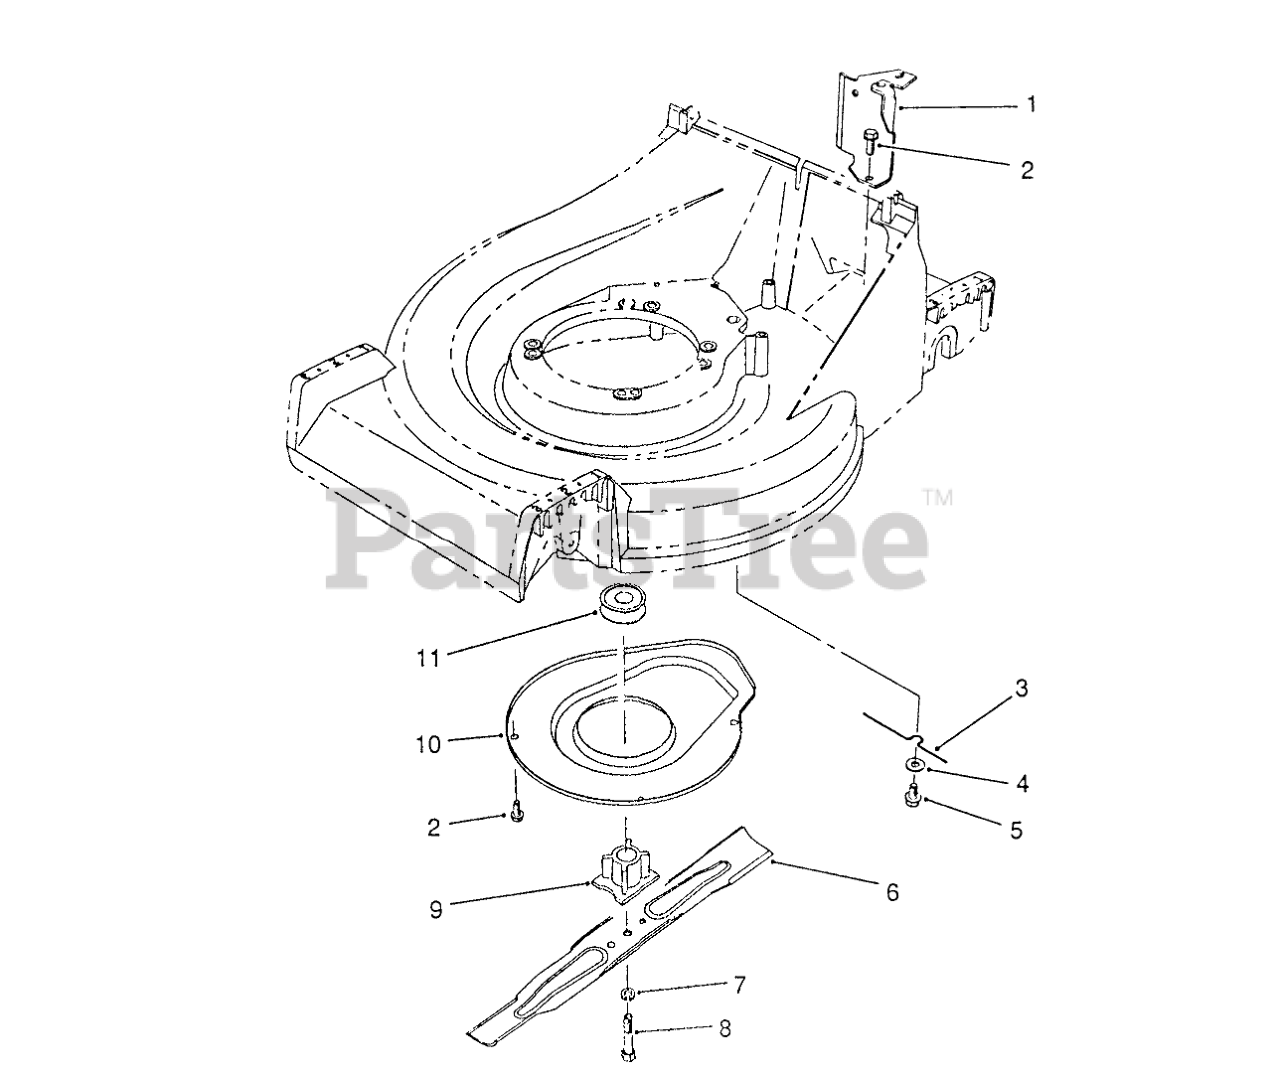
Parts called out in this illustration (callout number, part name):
1	Bracket-Cable Support
2	SCREW-HWHTF
3	RETAINER-BELT
4	WASHER-FLAT
5	SCREW-HHFTF
6	Key
7	WASHER-LOCK
8	SCREW-BLADE
9	BLADE RETAINER
10	Cover
11	PULLEY-DRIVE, ZONE START
